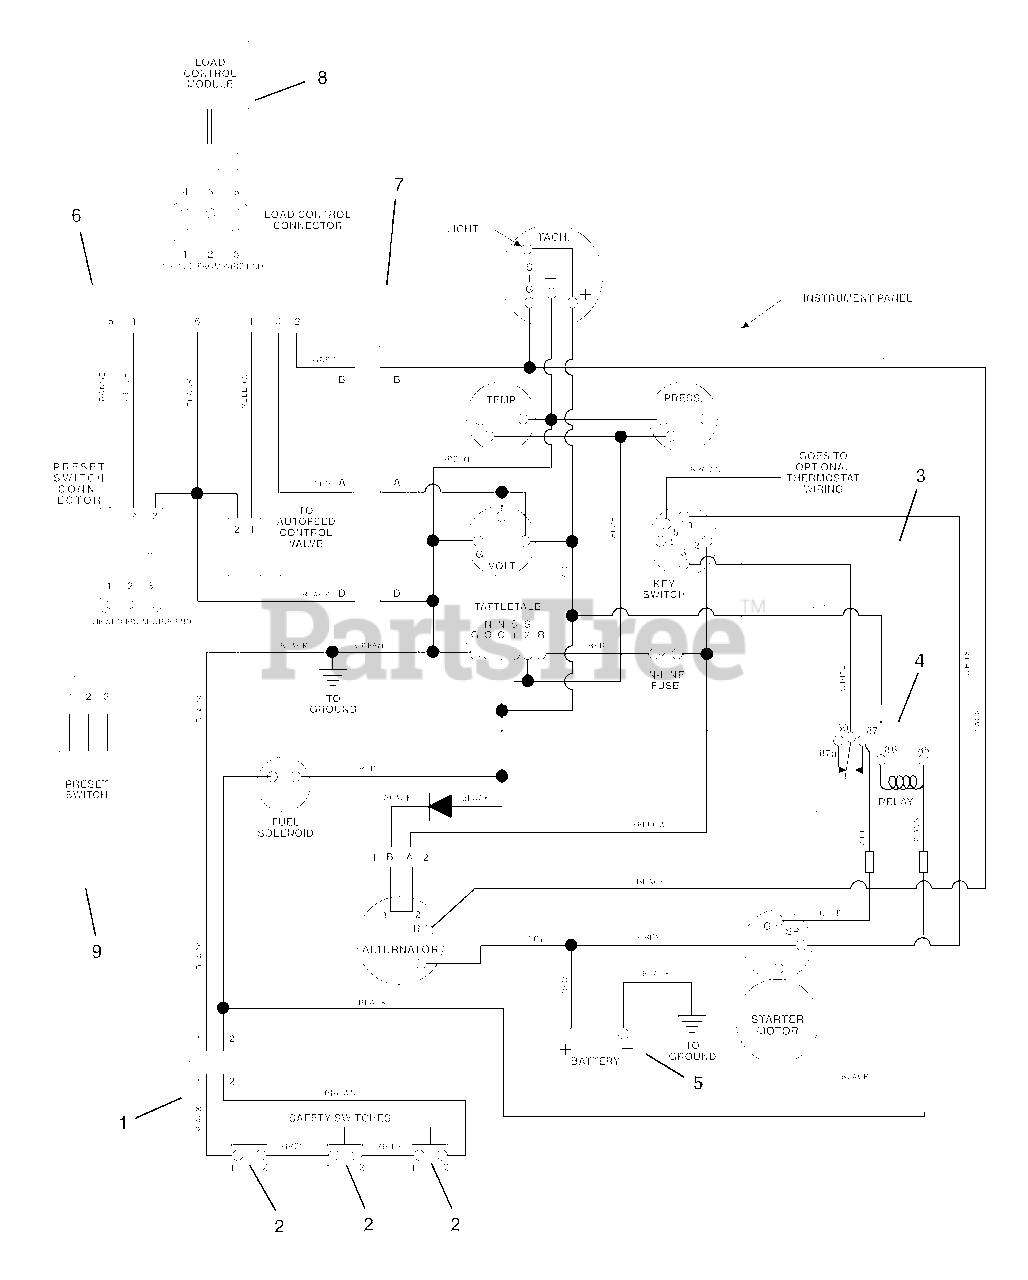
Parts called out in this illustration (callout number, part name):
1	Harness-Wiring, Safety Switch
2	Safety Switch
3	Harness-Relay/Safety
4	Relay
6	Harness-Wiring, 495 Autofeed
6	Harness-Wiring, Autofeed
7	Harness-Adapter, Autofeed
8	Module-Load Control
9	Pre-Set Switch
